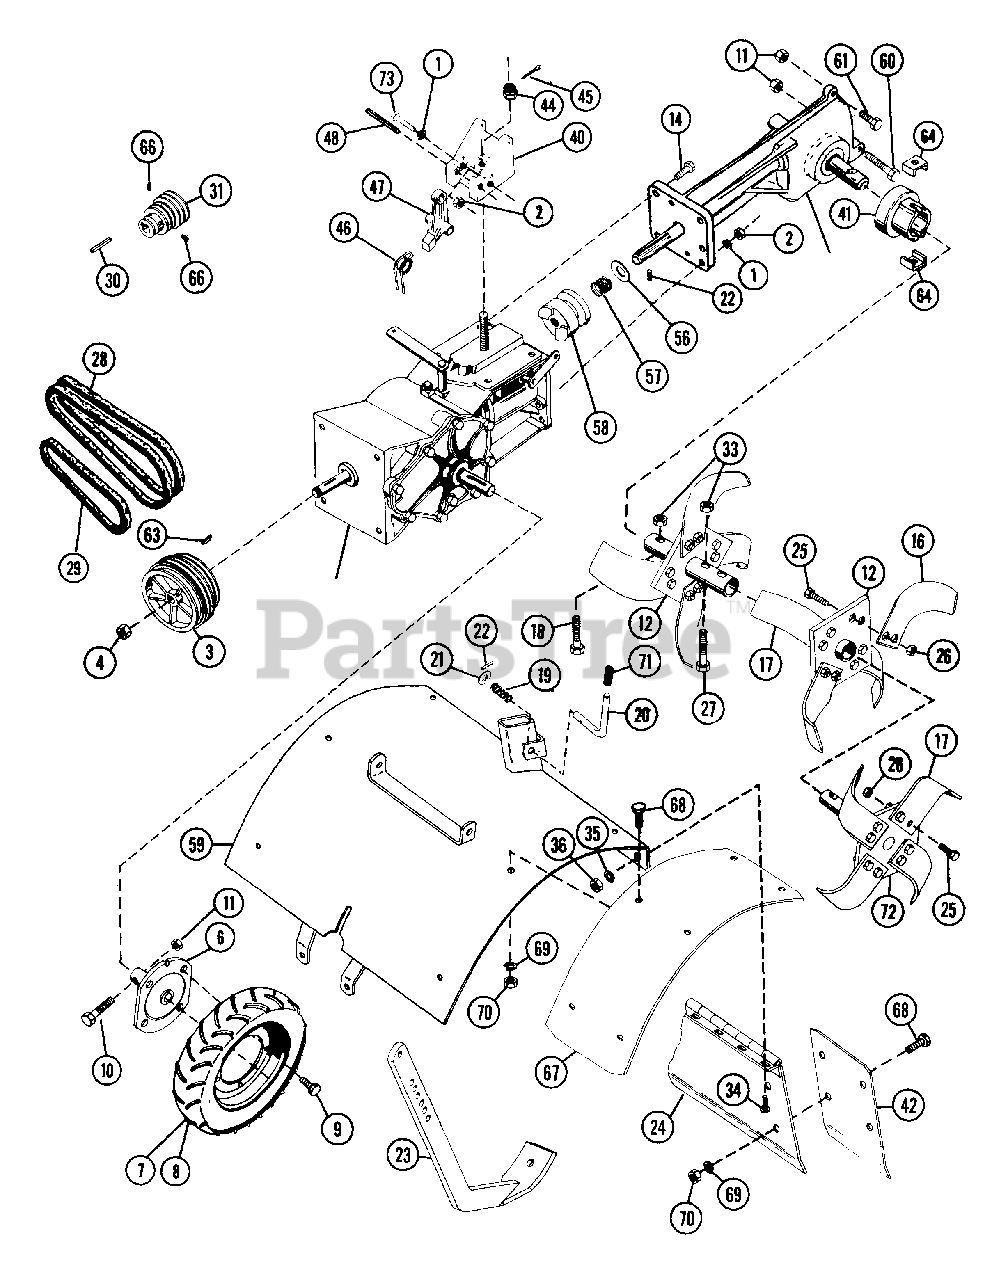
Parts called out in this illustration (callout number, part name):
1	WSHR-LK .375X.115 HVY PL
2	NUT-HEX .375-16
3	DRIVE SHEAVE
4	NUT-LK-CTR .75-16 PL
5	KEY-FTHR .25X1.875X.25 SAE
6	WHEEL HUB
7	R H TIRE AND RIM ASSY
8	L H TIRE AND RIM ASSY
9	SCR-TAP .500-20X.62 HH PL
10	BLT-HEX .31-18X2.00 PL GR2
11	NUT-LK .312-18 GR A PL
12	INNER TINE HUB
14	BLT-HEX .38-16X1.75 PL GR2
15	NUT-LK .375-16 PL
16	R KNIFE TINE
17	L KNIFE TINE
18	BLT-HEX .38-16X2.75 GR8
19	SG-COMP .045X.50X1.187
20	DEPTH REGULATING PIN
21	WSHR-FL-STL .38X.875X.083 PL
22	PIN-ROLL .125X1.00
23	DEPTH SHOE
24	TAILBOARD
25	BLT-HEX .44-14X1.00 GR5
26	NUT-LK-TOP .437-14 GR C PL
27	BLT-HEX .38-16X2.00 GR8
28	V-BELT, SAE 380-RAW EDGE (SET)
29	V-BELT, 3L-COGGED
30	KEY-SQ .25 X 1.25 X .25 SAE
31	ENGINE SHEAVE
33	NUT-LK TOP .375-16 GR C YWZC
34	BLT-RDHDSQSHNK .31-18X.50 YZ
35	WSHR-LK .313X.093 MED HICLR
36	NUT-HEX .312-18
40	HANDLEBAR BRACKET
41	DUST CAP
42	TAILBOARD EXTENSION
44	NUT-SL .50-13
45	PIN-COTR .12X1.0 PL
46	SG-TORS .109X.88X2.25
48	PIN-ROLL .313X2.00
56	WSHR-FL-STL .755X1.375X.125
57	SG-COMP .080X.97X2.18 WLD14
58	TILLER JAW CLUTCH
59	TINE HOOD WITH DECALS
60	BLT-HEX .31-18X3.50 PL GR2
61	BLT-HEX .31-18X1.25 PL GR2
65	BLT-HEX .38-16X2.00 PL GR2
66	SCR-SET .32-18X.38 SKHCUPNL OH
67	TINE HOOD EXTENSION
68	BLT-HEX .25-20X.50 PL GR2
69	WSHR-LK .250X.077 HVY PL
70	NUT-HEX .250-20 PL
72	OUTER TINE HUB
73	BLT-HEX .38-16X1.00 PL
